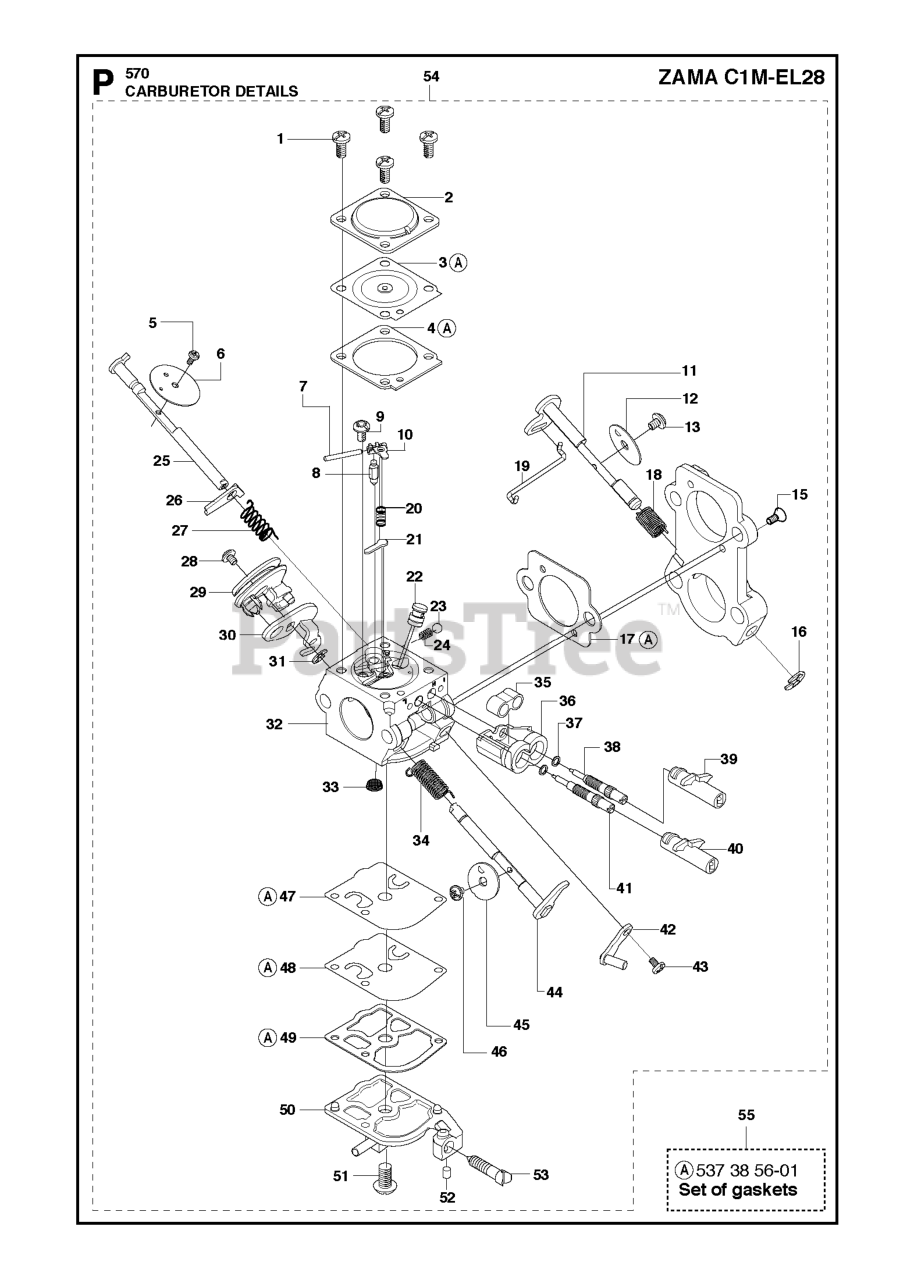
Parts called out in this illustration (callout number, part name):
6	CHOKE FLAP
7	PIN RETAINING SCREW
8	INLET NEEDLE
12	THROTTLE FLAP
25	CHOKE SHAFT
32	RP CARBURETOR
38	NEEDLE HIGH SPEED
41	LOW SPEED NEEDLE
44	THROTTLE SHAFT
47	PUMP DIAPHRAGM
54	RP CARBURETOR
55	GASKET SET
